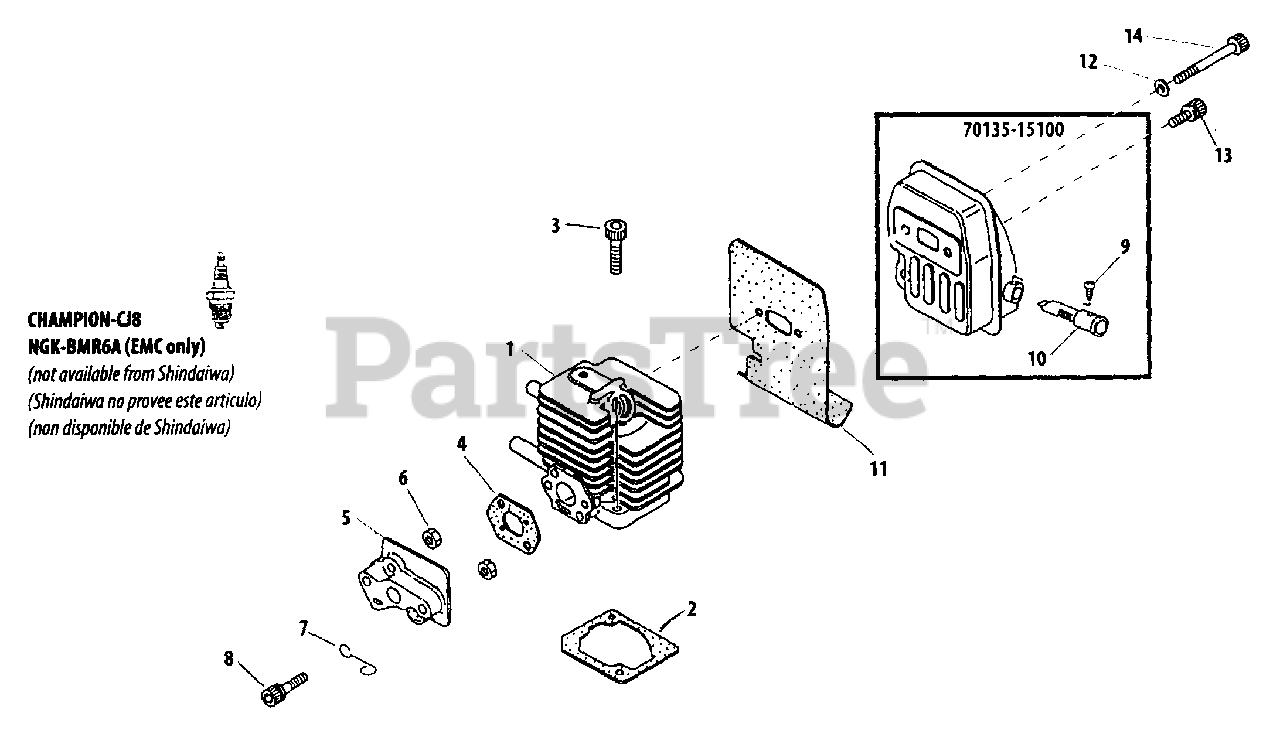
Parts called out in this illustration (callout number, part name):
1	CYLINDER
2	GASKET, CYLINDER
3	BOLT 5×25
4	GASKET
5	INSULATOR BLOCK
6	NUT M5
7	CLIP, VENT ASSY
8	BOLT SS M5×30
9	SCREW, TAPPING 3×6
10	SCREEN, SPARK ARRESTER
11	GASKET, EXHAUST
12	WASHER, FLAT 5.5×10×0.8
13	BOLT 5×12
14	BOLT M5×50
70135-15100	MUFFLER ASSY
